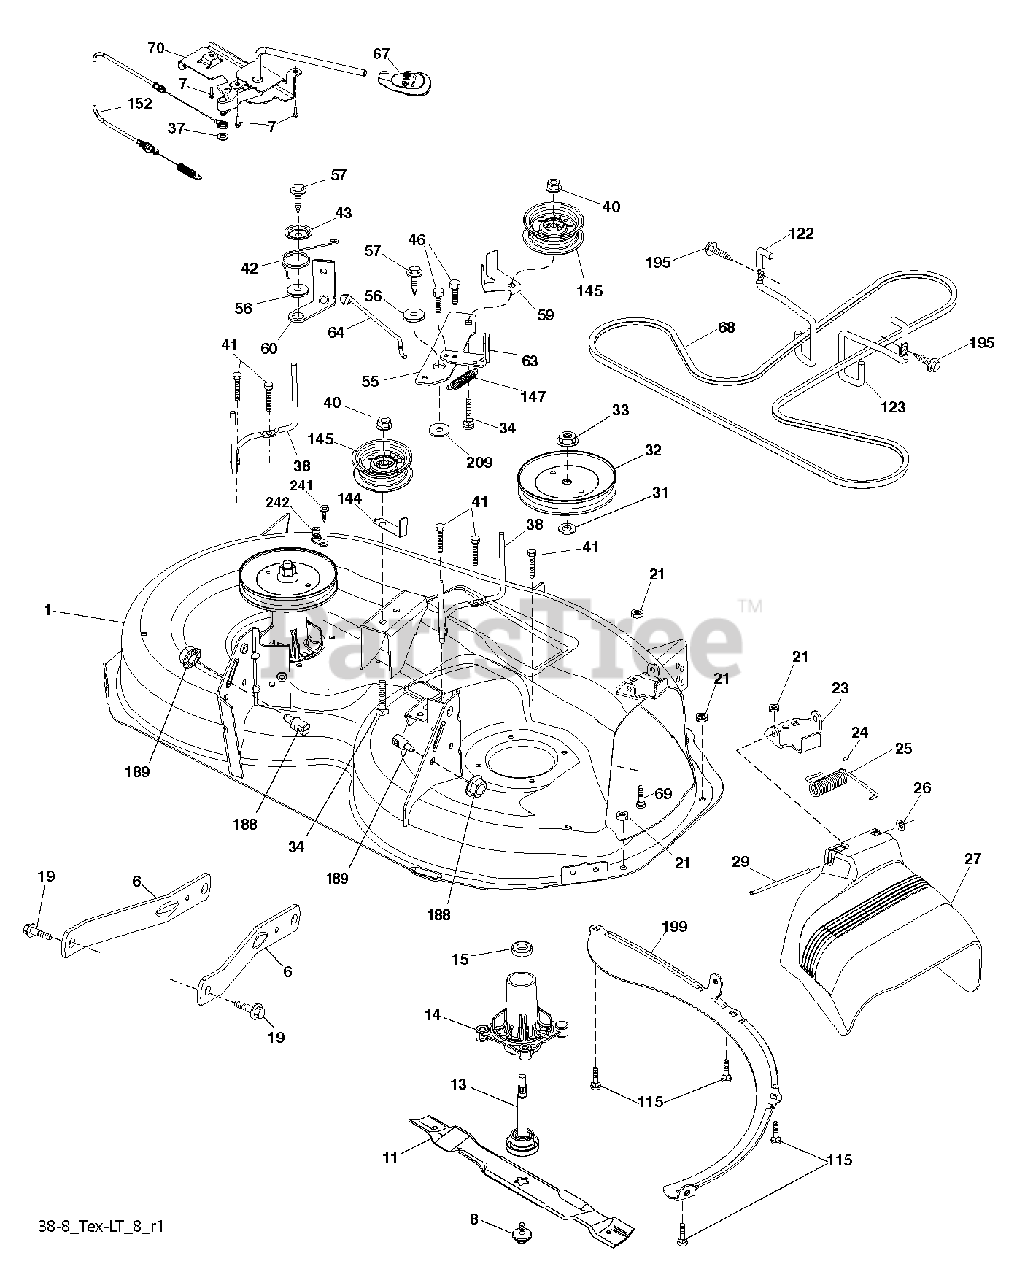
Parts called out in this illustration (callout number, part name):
1	DECK.WELDMENT.38"TEX.N/GWB.BLU
6	ARM.SUSPENSION.MOWER.R
7	SCREW.#10 X 0.750.BOS (2 2)
8	BOLT.WASHER.ASM.7/16-2
11	BLADE 38" PREMIUM
13	SHAFT.ASM.MDRL.N/GREASE.38
14	HOUSING.MANDREL.4PT.
15	BEARING
19	BOLT.SHOULDER
21	LOCKNUT
23	BRKT.DEFLECTOR.38"2005+
24	CAP-SLEEVE LT
25	SPRING.TORSION.DEFLECT
26	NUT PUSH M
29	ROD.HINGE
31	WASHER.SPACER.MANDREL
32	PULLEY.MANDREL.5.0.PD.38"
33	NUT.FLANGE.LOCK.TOP
34	BOLT.3/8-16X1.50
37	WASHER
38	KEEPER BELT LH MANDREL
40	NUT LOCK FLG 3/8-16 UNC
41	BOLT.HEX.WASHR.HED.313-18X1.19
42	SPRING.TORSION.BRAKE
43	SRPING.TORSION.RETAINE
46	SCREW.1/4-20X5/8
55	IDLER.ARM
56	SPACER.RETAINER
57	SCREW 3/8-16X1
59	GUARD, BELT
60	ARM BRAKE MOWER RH 38"
63	ARM BRAKE MOWER RH
64	LINK BRAKE
67	HANDLE.CLUTCH.CABLE.LT
69	BOLT
70	CLUTCH.ASM.MANUAL.LT.PRED
115	BOLT
122	KEEPER BELT ENGINE LH
123	KEEPER BELT RH
144	KEEPER BELT
145	PULLEY.IDLER.48"PRIMARY
147	SPRING RETURN
152	CABLE.CLUTCH.MANUAL.
188	STUD.FASTNER.W/ANTI-ROTATE
189	NUT LOCK HEX FLANGE 5/16-18
195	SCREW, 3/8-16X3/4
199	BAFFLE.VORTEX.FRONT.38"
209	WASHER 12/32X2X10GA
241	SCREW.TT.#10-32X.5.3/8.FLANGE
242	PORT.WASHOUT
